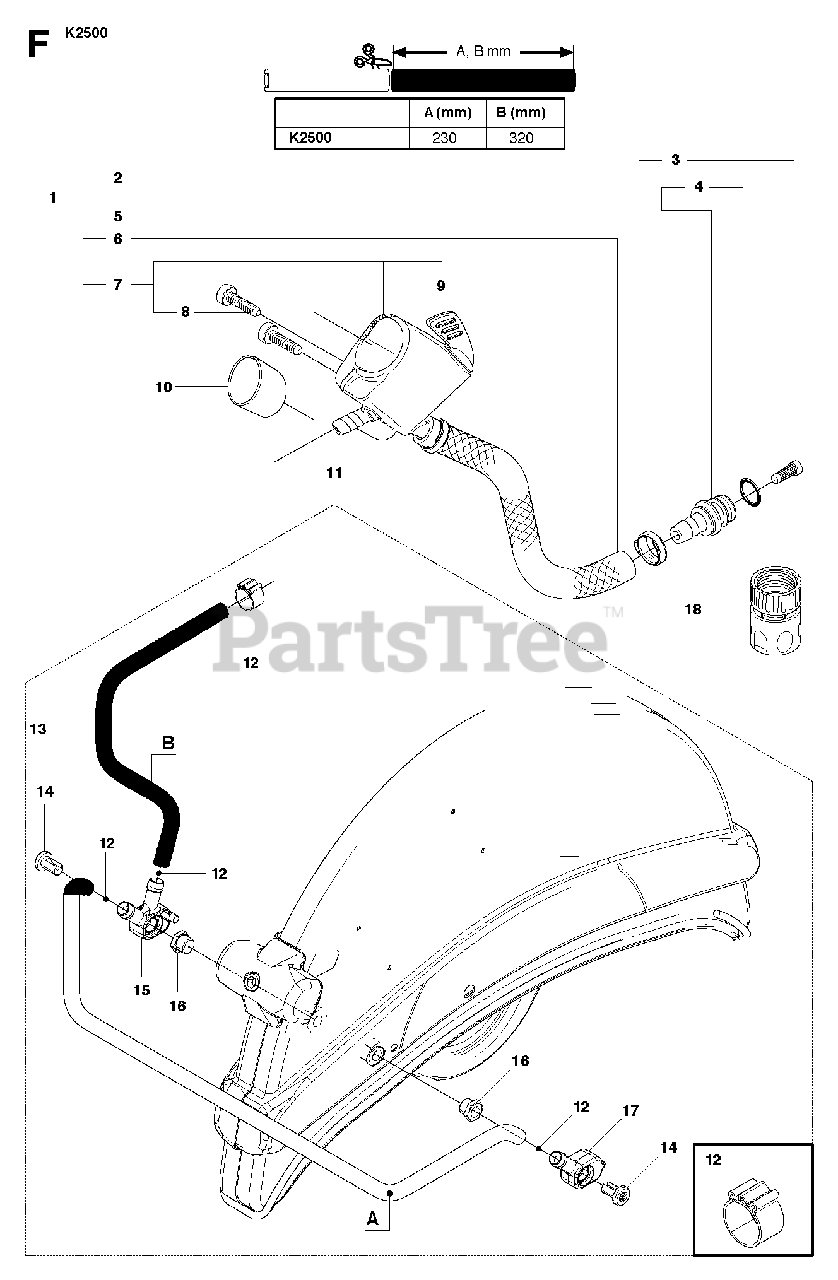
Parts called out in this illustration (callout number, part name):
2	NIPPLEIncl. 2, 5 - 7 (New Part)
3	FILTERIncl. 3, 4
5	HOSE CLAMP
7	VALVE ASSYIncl. 8
8	SCREW ITXSCTNew Part
9	VALVE SPINDLENew Part
11	HOSE KITIncl. 11 - 16
13	HOSE620 mm
14	SCREW ITXSCM
18	COUPLER1 USA, Canada
